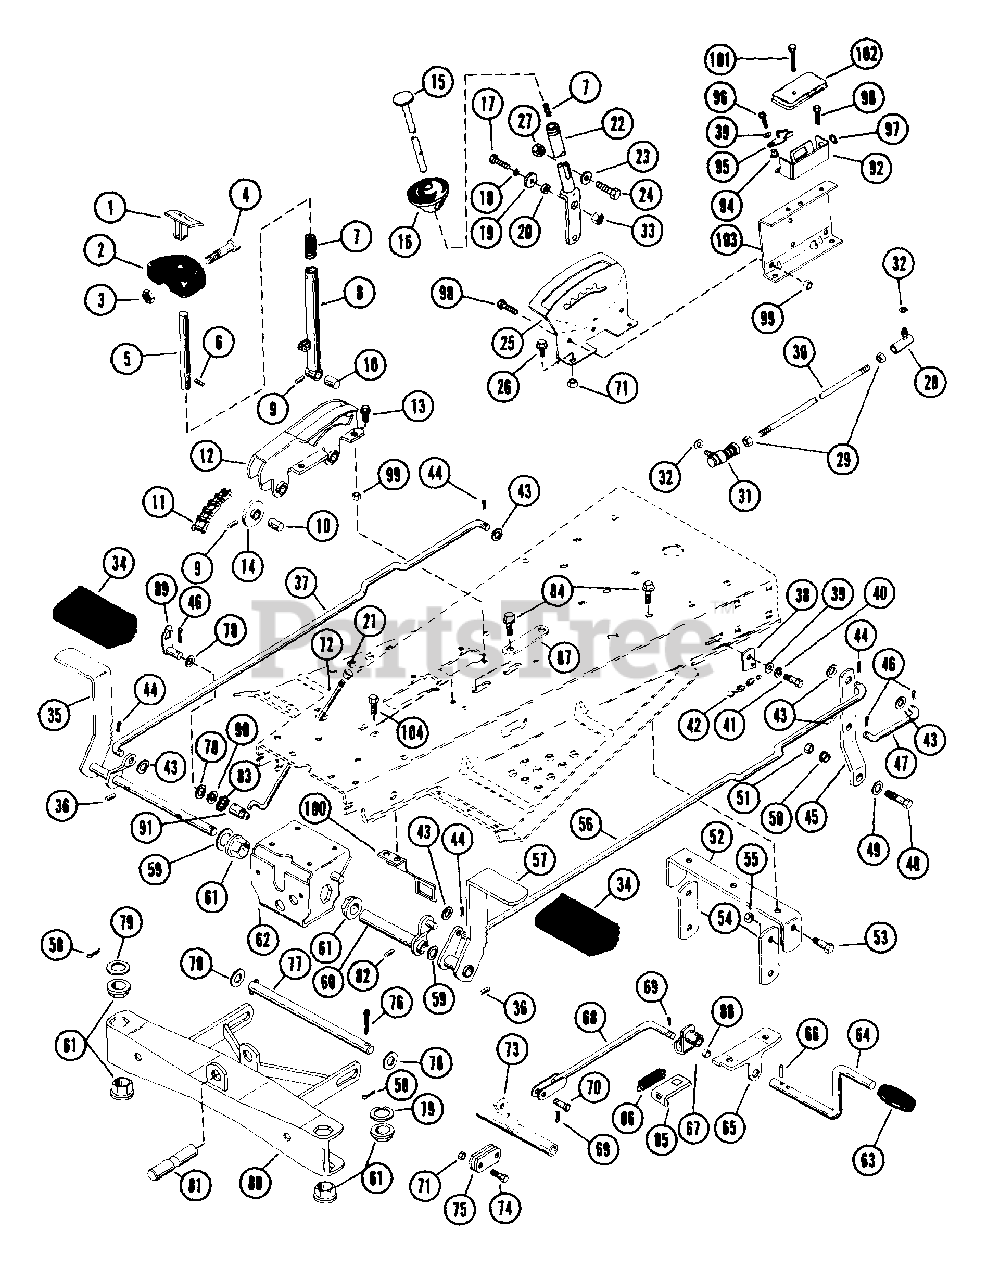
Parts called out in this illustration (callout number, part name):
1	T PLUNGER
2	T HANDLE
3	NUT-LK TOP 10-24 PL
4	BLT-HEX 10-24X1.25 FHPL
6	PIN-ROLL .250X1.25
7	SG-COMP ??X.44X?? WLD 10
8	MOWER LIFT ARM
9	PIN-ROLL .125X.75
11	ROLLER CHAIN
12	MOWER HEIGHT QUADRANT
13	BLT-HEX .25-20X.50 PL GR2
14	CHAIN ROLLER
15	SHIFT RELEASE HANDLE
16	SHIFT BALL
17	BLT-HEX .31-18X1.00 PL GR 2
18	WSHR-LK .312X.097 PL HVY
19	WSHR-FL-STL .38X.875X.083 PL
20	SPACER BUSHING .5 X .32 X .21
22	SHIFT LEVER
23	WSHR-FL-STL .281X1.250X.048PL
24	BLT-HEX .25-20X1.25
25	SHIFT CONTROL SEGMENT
26	BLT-SERHFWH .31-18X.50 PL
27	NUT-LK TOP .250-20 PL
28	BALL JOINT
29	NUT-HEX .312-24 PL
30	SHIFT LINK
31	SNAP IN BALL JOINT
32	WSHR-LK .312X.097 PL HVY
33	NUT-HEX .312-18
34	PEDAL COVER
35	BRAKE LEVER
36	PIN-ROLL .125X1.00
37	BRAKE ROD
38	BLADE BRAKE
39	WSHR-FL-STL .38X.875X.083 PL
40	WSHR-LK .312X.097 PL HVY
41	BLT-HEX .31-18X.75 PL GR2
42	CHAIN
43	WSHR-FL-STL .382X.812X.023 PL
44	PIN-COTR .09X.75 PL
45	CLUTCH LINK BAR
46	PIN-COTR .12X1.0 PL
47	CLUTCH LINKAGE ROD
48	BLT-HEX .38-16X.75 PL GR2
49	WSHR-FL-STL .630X1.005X.062 PL
50	SHOULDER SPACER
51	NUT-LK-CTR .375-16 GR A PL
52	HANGER BRACKET
53	SHOULDER BOLT
54	HANGER LINK
55	NUT-LK-CTR .375-16 GR A PL
56	CLUTCH ROD
57	CLUTCH BRAKE LEVER
58	PIN-COTR .12 X 1.25 PL
59	WSHR-FL-STL .505X.875X.024 PL
60	CLUTCH BRAKE LEVER
61	FLANGE BUSHING
62	AXLE SUPPORT
64	MOWER CLUTCH PEDAL
65	MOWER CLUTCH BRACKET
66	PIN-ROLL .188X1.00
67	OVER CENTER LEVER
68	MOWER CLUTCH LINK
69	PIN-COTR .09X.75 PL
70	CLEVIS PIN
71	NUT-LK .312-18 GR A PL
72	PARKING BRAKE ROD
73	MOWER CLUTCH LEVER
74	BLT-HEX .31-18X.75 PL GR2
75	FRONT LINK
76	PIN-COTR .12X1.0 PL
77	HANGER PIN
78	WSHR-FL-STL .531X1.062X.095 PL
79	WSHR-FL-STL .755X1.375X.062 PL
80	FRONT AXLE
81	AXLE PIVOT PIN
82	PIN-ROLL .188X.88
83	WAVE WASHER .531X.781X.125FH
84	BLT-SCRHFWH .38-16X.50 PL
85	SPRING CLIP
86	SG-TENS .062X.437X4.81 WLD 6
87	GUIDE PLATE
89	BRAKE LATCH
90	WSHR-FL-STL .505X.875X.024 PL
91	BRAKE RELEASE LEVER
92	SWITCH HOUSING
93	SCR-TAP 10-24X.375 CRPH 1A
94	BSHG, FLG .325X.499X.26X.88
95	CAM NO SCRAP
96	BLT-SERHFWH .31-18X.75 PL
97	GROMMET, .31 ID
98	BLT-HEX .25-20X.75 PL GR2
99	NUT-LK-CTR .250-20 PL
100	SWITCH BRACKET
101	SCR-TAP 12-14X1.25 CROVH PL 1A
103	SWITCH BRACKET
104	BLT-SERHFWH .25-20X.50 PL
